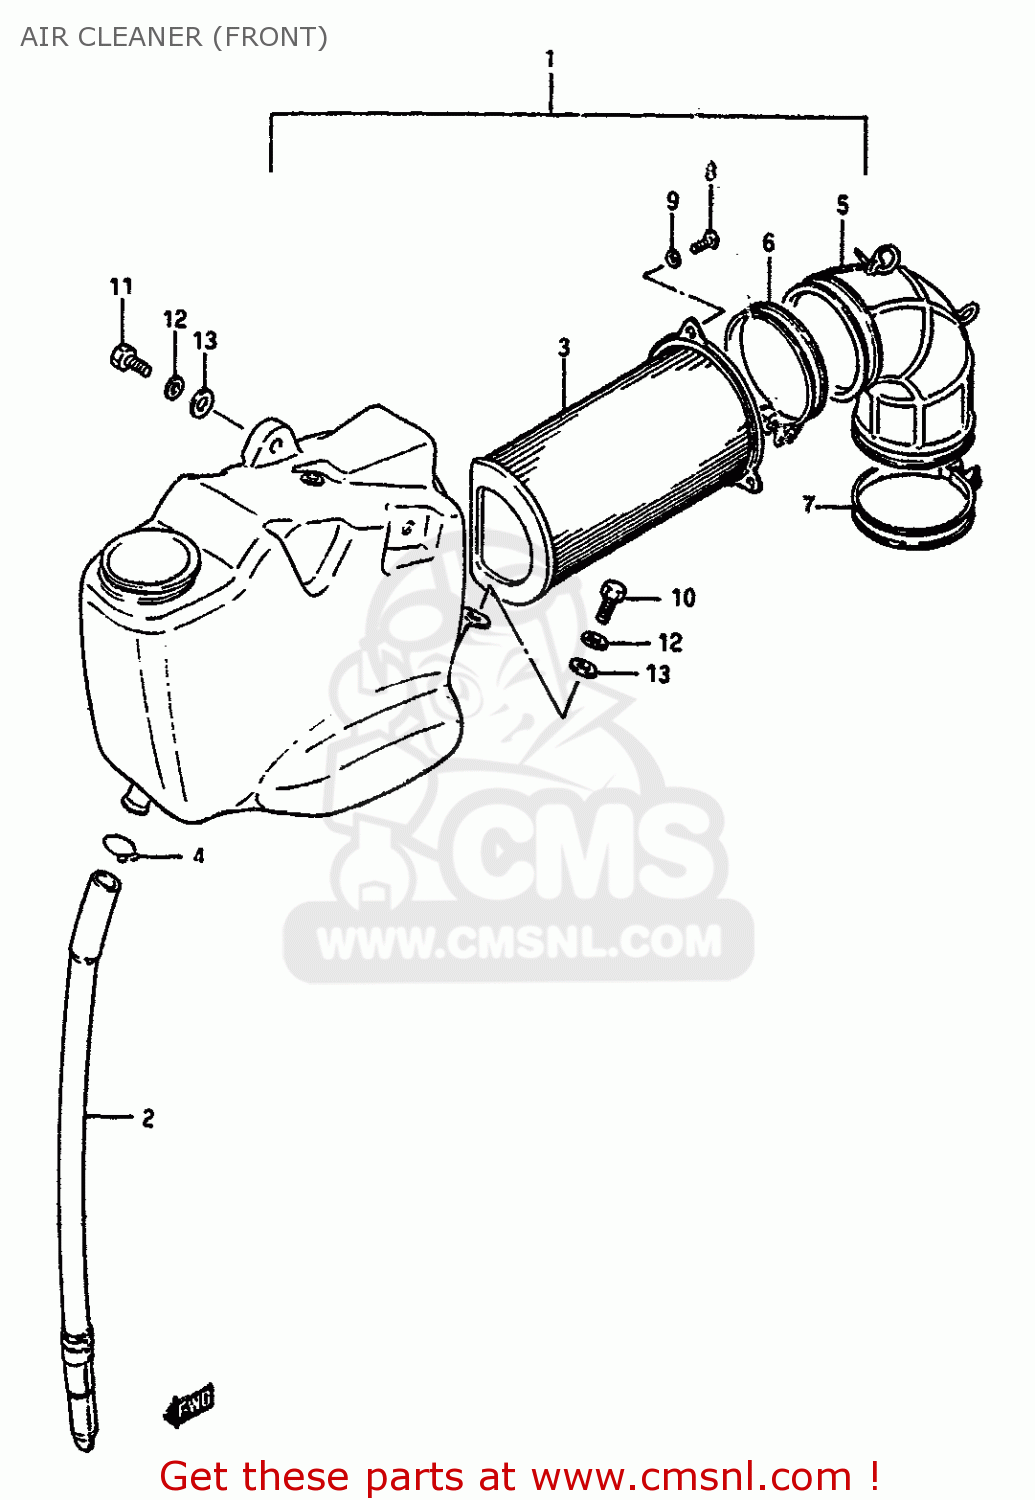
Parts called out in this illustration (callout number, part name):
1	CLEANER ASSEMBLY,AIR
2	DRAIN TUBE
3	FILTER,AIR CLEANER
4	CLIP
5	TUBE,AIR CLEANER OUTLET
6	CLAMP
7	CLAMP
8	SCREW
9	LOCK WASHER
10	BOLT
11	BOLT
12	WASHER,LOCK
13	WASHER
